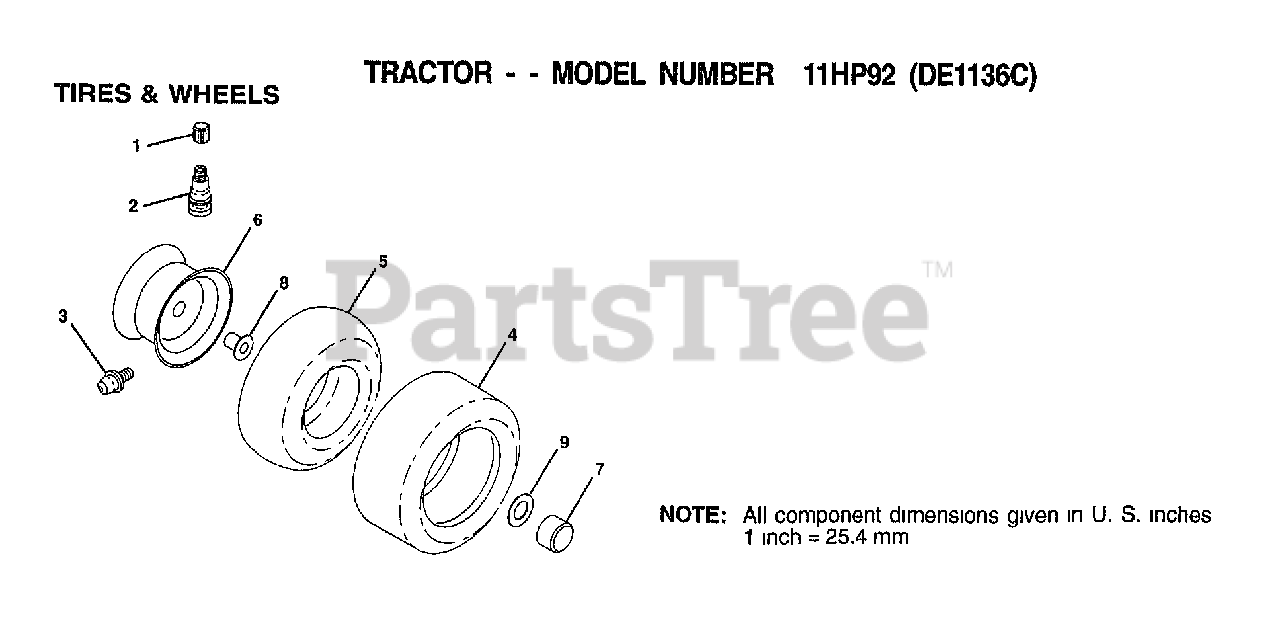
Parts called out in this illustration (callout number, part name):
1	VALVE CAP
2	VALVE STEM LT
3	FITTING LT
5	TUBE.5.3/4.5/6
5	TUBE.16X6.5/7.5-8
6	"RIM.FRT.6"".ASM"
6	"RIM REAR 8"""
7	HUB CAP
8	"FLANGE, BEARING"
9	WASHER
